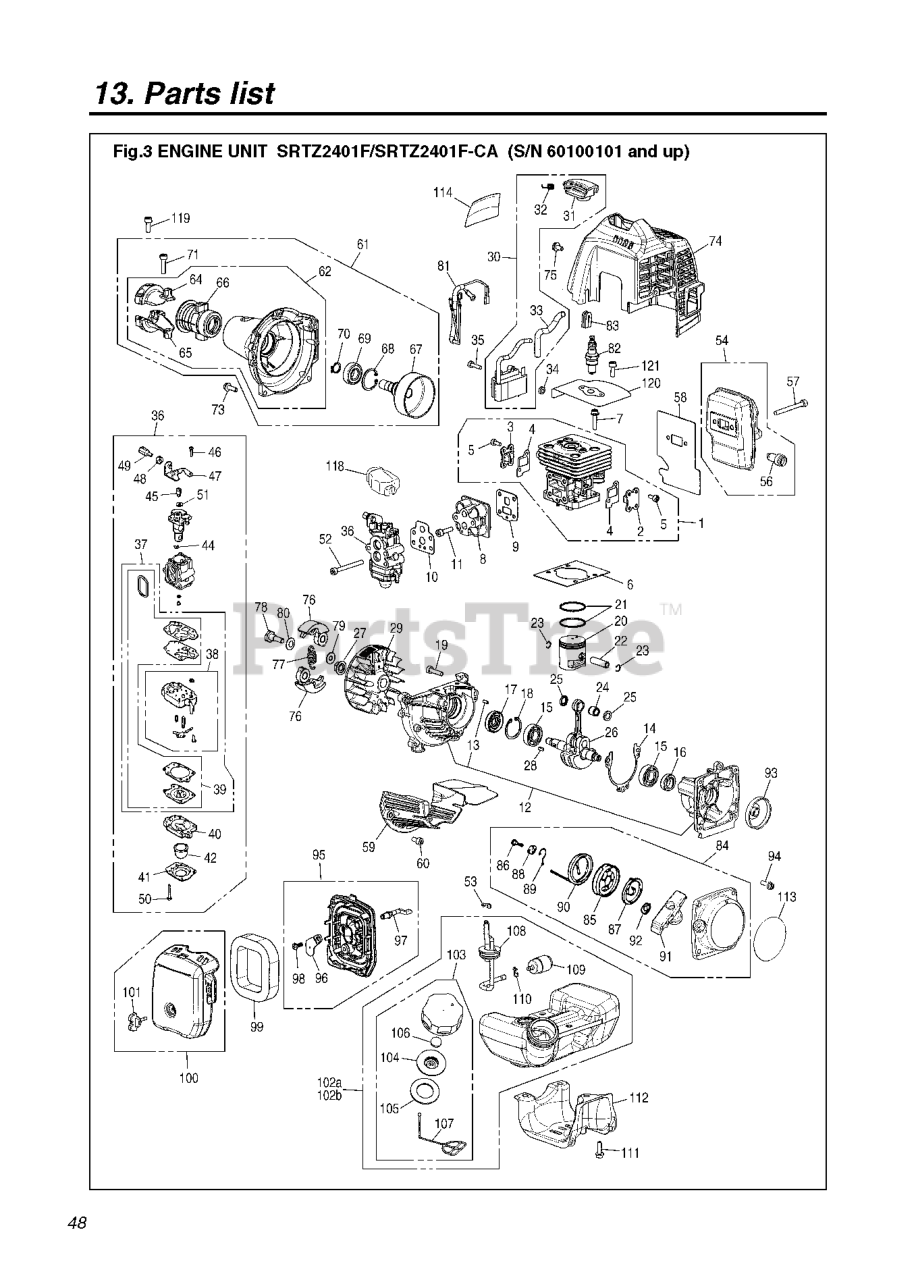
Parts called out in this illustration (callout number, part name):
1	CYLINDER COMPLETE
2	COVER, TR-S
3	COVER, TR-F
4	GASKET, TR
5	BOLT
6	GASKET, BASE
7	BOLT
8	INSULATOR
9	INSULATOR GASKET(R-848F0814B0)
10	GASKET, CARB
11	BOLT TORX
12	CRANKCASE-C
13	PIN
14	GASKET, CASE
17	SEAL
22	PIN
26	CRANKSHAFT-C
27	NUT
28	KEY
30	IGNITION COIL
31	CAP
34	SPACER
36	CARBURETOR (RPLS 848F088100)
37	REBUILD KIT
38	CARBURETOR BODY
39	GASKET KIT
41	1OVER
44	RING
45	SWIVEL
46	SCREW
47	BRACKET
48	NUT
49	ADJUSTER
51	WASHER
53	CLIP
54	MUFFLER-A***
56	ARRESTER
58	GASKET, MUFFLER
61	HOUSING ASSY (RPLS T155131000)
62	HOUSING
64	BRACKET (A) (RPLS T170031211)
65	BRACKET (B)
67	DRUM (RPLS 481031120-22)
69	BEARING
74	COVER, ENGINE
75	BOLT (RPLS T495051010-11)
81	CORD-COMP
82	PLUG CMR7H
84	RECOIL ASSY
87	SPRING, SPIRAL
88	COLLAR
89	SWING ARM
92	PLATE.STOPPER
95	BODY ASSY
96	PLATE.CHOKE
97	LEVER CHOKE
98	SCREW
100	COVER-A (RPLS T155182200)
103	CAP A
104	HOLDER-A
108	PIPE-C
109	FILTER ASSY
110	CLIP
114	LABEL COVER
